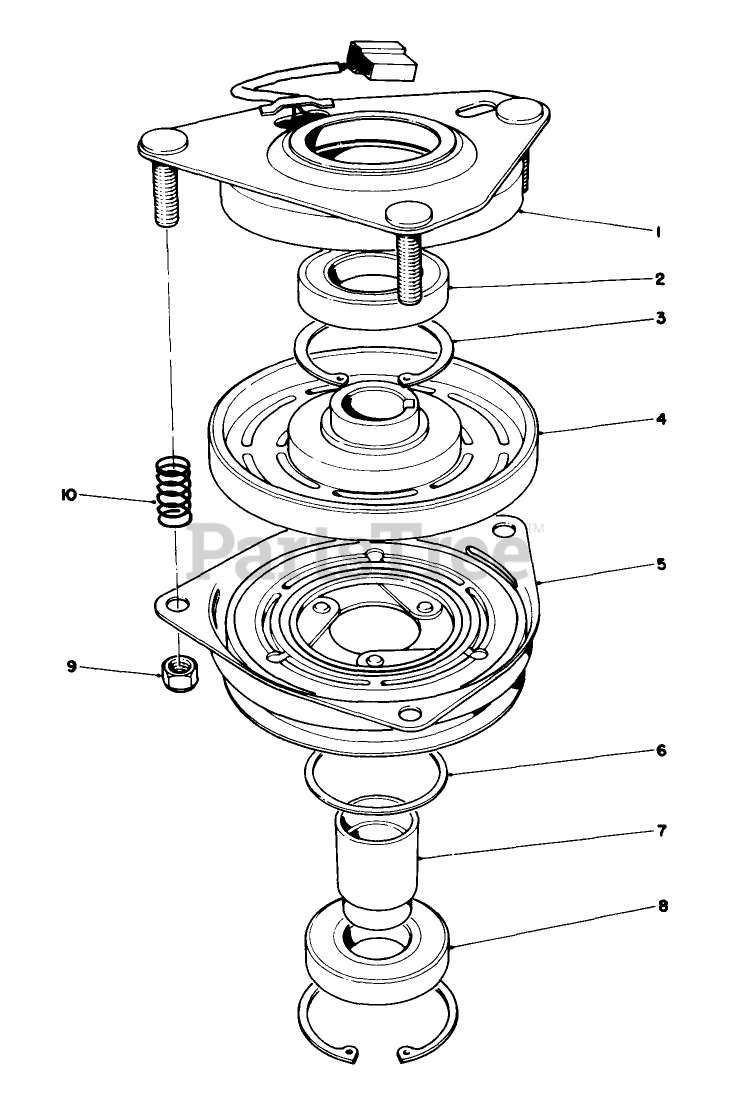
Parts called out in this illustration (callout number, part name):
1	FIELD BEARING ASM
2	BEARING-FIELD
3	RING-RETAINING
4	FIELD COIL/ROTOR BEARING ASM
6	SPACER-BEARING, PULLEY
7	COLLAR-BEARING
9	NUT-LOCK
10	SPRING
